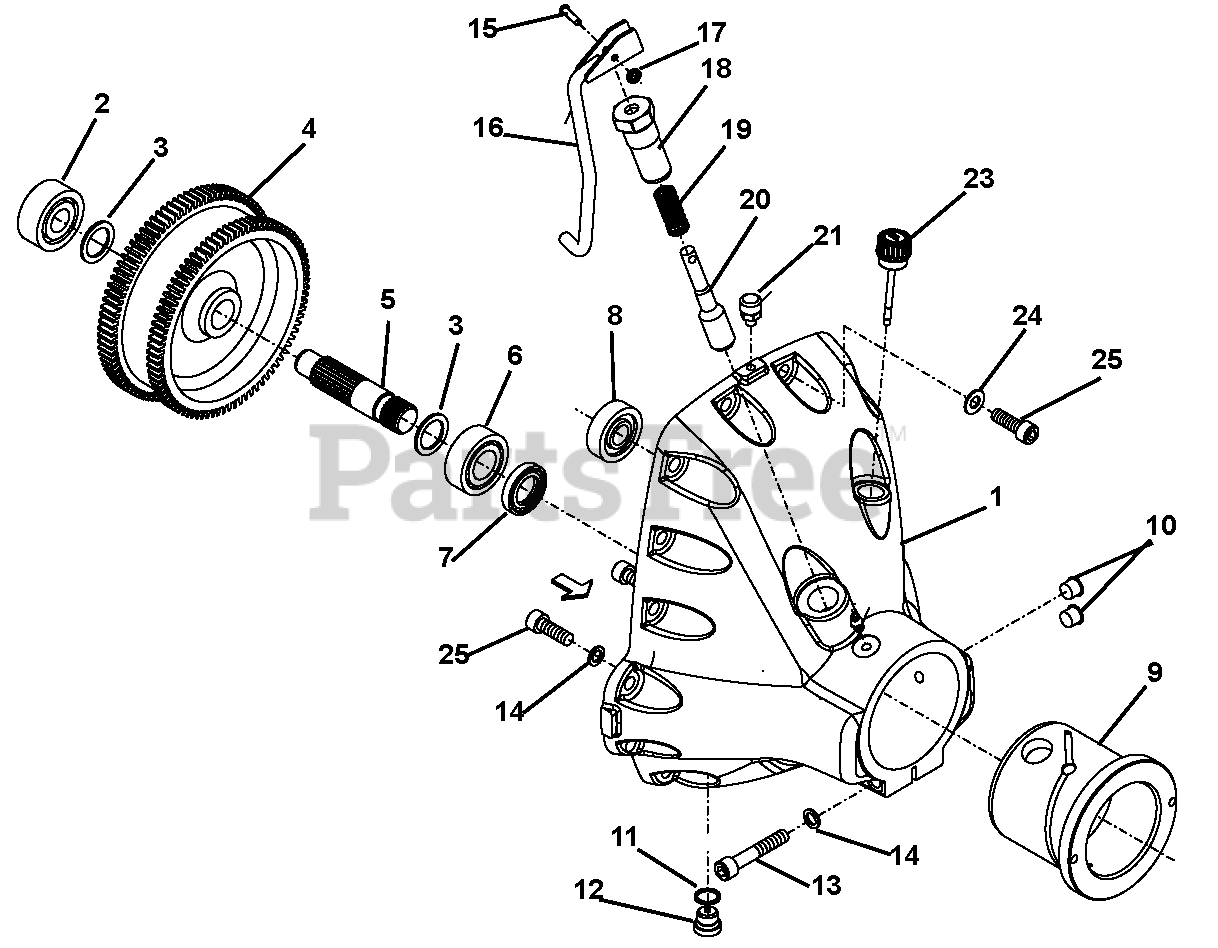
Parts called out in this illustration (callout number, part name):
1	P.T.O, Case
2	Bearing, Ball NJ 2304E
3	Washer, D988 25 x 35 x 2
4	Pinion, Double Z=83/88
5	P.T.O. Power
6	Bearing, Ball 4205B.TVH
7	Seal, Oil D3760 25 x 42 x 7 AS
8	Bearing, Ball NJ 303E
11	Ring, Joint D7603A 16 x 20 CU
12	Drain, Plug D908 Metric 16 x 1.5MG
13	Screw, D912 M10 x 60
14	Washer, FORM Z 10.2/16.1 x 1.6
15	Pin, Lock D1444A 5 x 25
17	Circlip, BQ-DL5
18	Guide Tube
19	Spring, Pressure 1.6/15.1 x 60
20	Bar, Lock
21	Filter, Breather
22	Lubricator, D71412A M8 x 1
23	Oil Gauge with Gasket
24	Washer, Form Steel 10.2/20.25 x 1.6
25	Screw, D912 M10 x 30
